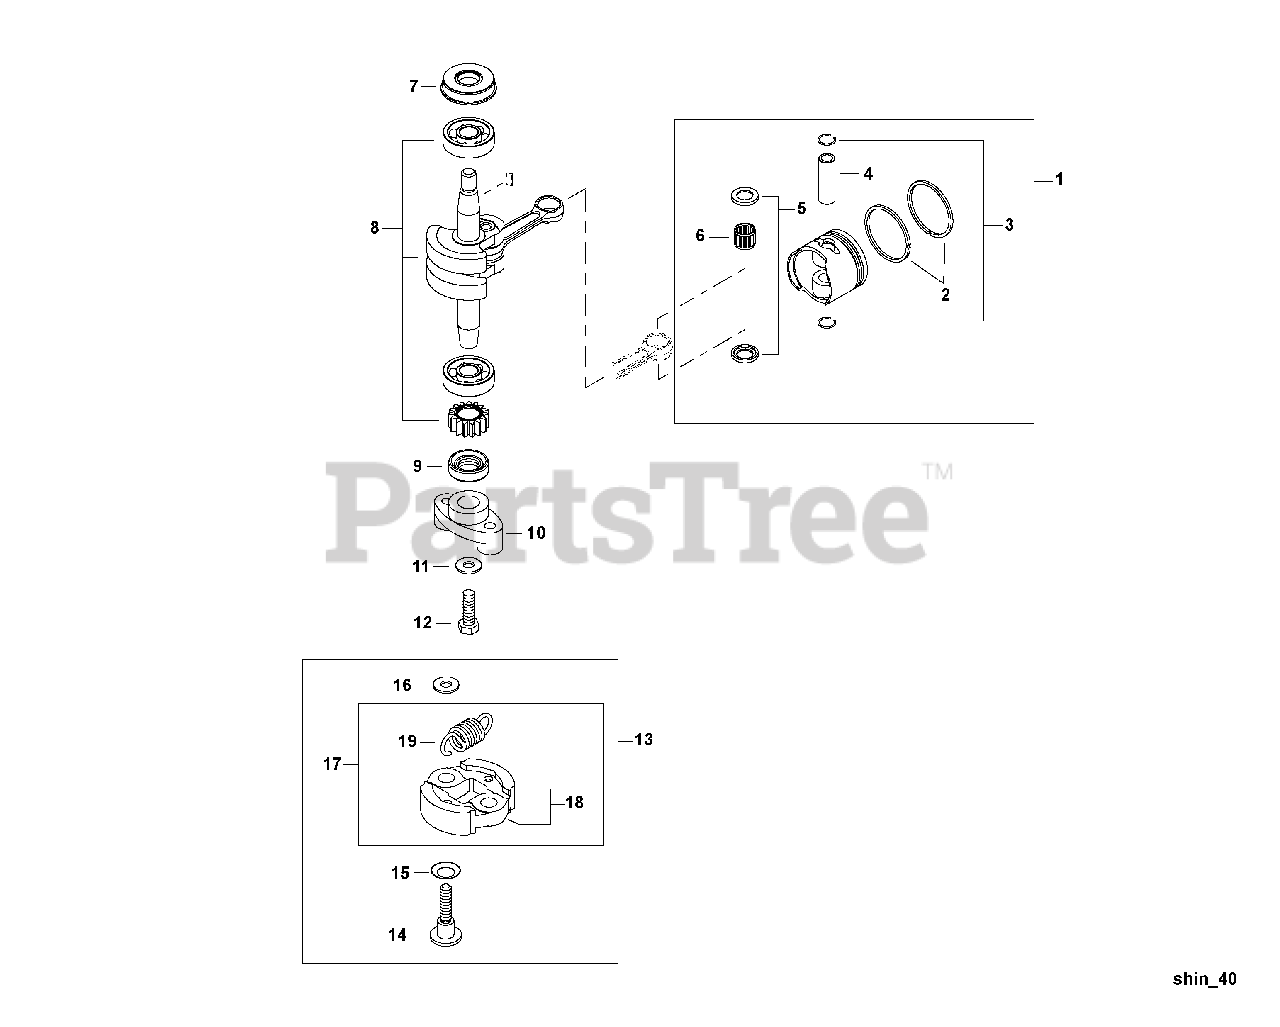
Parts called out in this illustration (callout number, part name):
1	PISTON KIT
2	RING, PISTON
3	RING, RETAINING
4	PIN, PISTON
5	SPACER - 9
6	BEARING, NEEDLE
7	SEAL, OIL
8	CRANKSHAFT ASSY
9	SEAL, OIL - 12
10	HUB, CLUTCH
11	WASHER - 6
12	SCREW - 6X18
13	CLUTCH ASSY
14	BOLT, CLUTCH
15	WASHER - SPRING
16	WASHER - 6
17	CLUTCH ASSY
18	SHOE, CLUTCH
19	SPRING, CLUTCH
